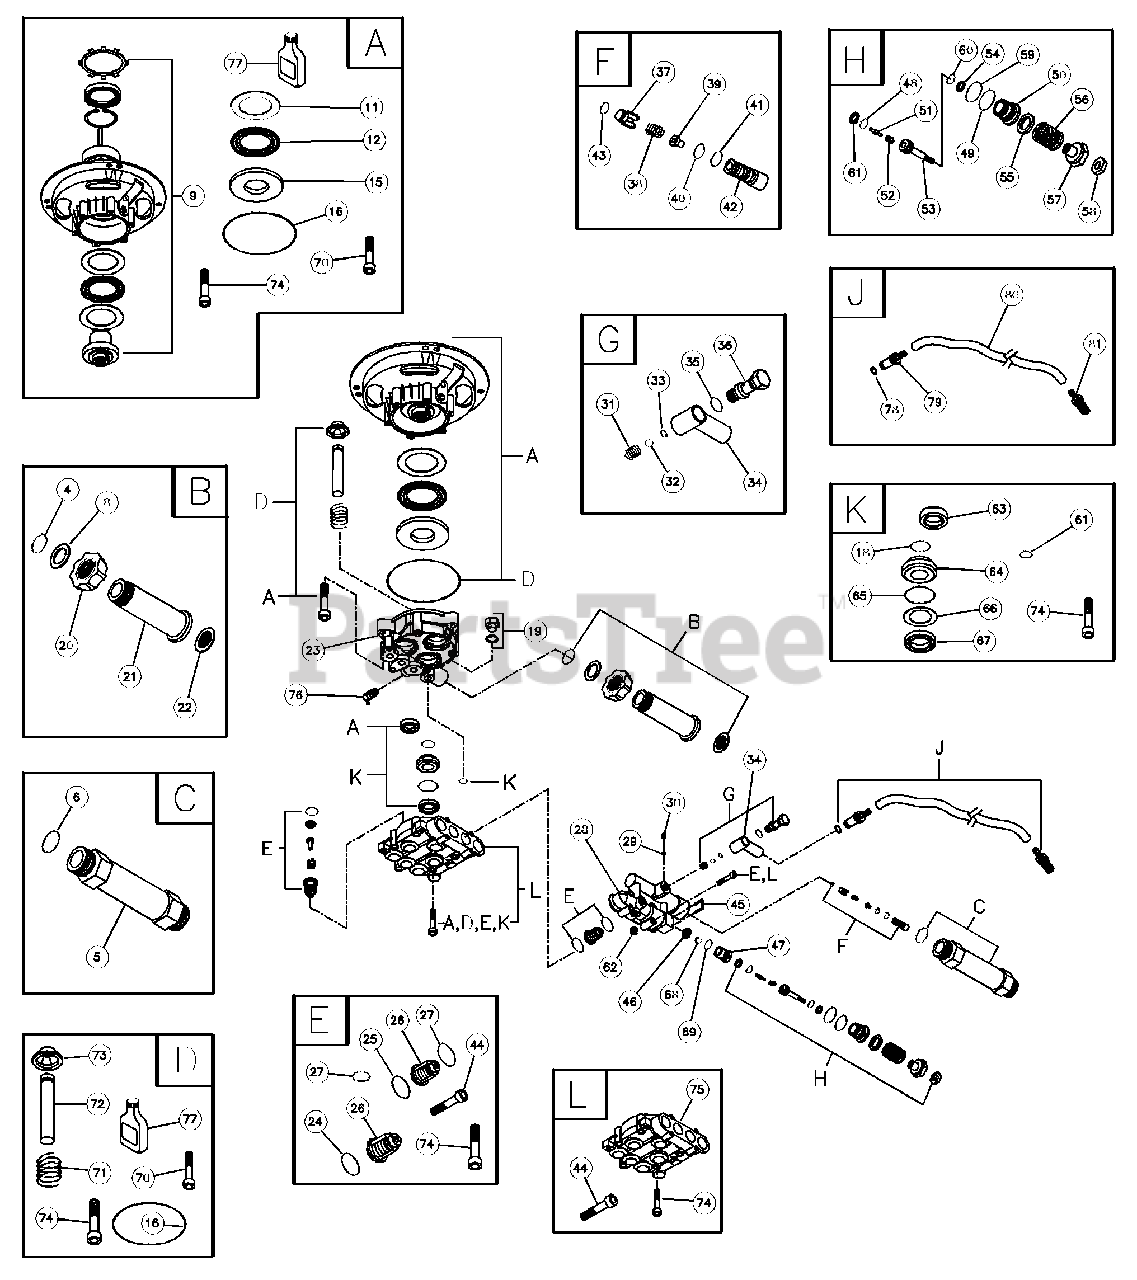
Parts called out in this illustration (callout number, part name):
4	O-RING
5	OUTLET EXTENTION
6	O-RING
8	WASHER
9	ASSY, Engine Adapter
11	FLAT BEARING DISC
12	ROLLER BEARING
15	FLAT BEARING DISC
16	O-RING
18	O-RING
20	GARDEN HOSE w/ FINGER GRIP
21	EXTENSION, INLET
22	WASHER w/ FILTER
24	O-RING
25	O-RING
26	ASSY, Valve Group
27	O-RING
29	O-RING
30	SCREW
31	SPRING
32	BALL
33	O-RING
34	CONNECTION, Chemical Inlet
35	O-RING
36	SCREW, Fitting
37	VALVE, Non-Return
38	SPRING
39	INJECTION NOZZLE
40	O-RING
41	O-RING
42	INJECTION NIPPLE
43	O-RING
44	SCREW
46	VALVE, Seat Plate, Brass
47	VALVE, Seat, Stainless
48	BACK RING
49	O-RING
50	VALVE, By Pass, Brass
51	PISTON
52	SPRING, Easy Start
53	PISTON, Body
54	RING, Back
55	SPACER
56	SPRING, Regulation Press
57	NUT, Regulation Press
58	NUT
59	O-RING
60	O-RING
61	O-RING
63	SEAL
64	PILOT SPACER, Brass
65	O-RING
66	WASHER
67	SEAL, H.P.
68	BALL, Stainless Steel
69	O-RING
70	SCREW
71	SPRING
72	PISTON, Stainless Steel
73	SPRING PLATE
74	SCREW
75	HEAD, Pump
76	THERMO RELIEF
77	OIL BOTTLE
78	O-RING
79	TUBE, Inlet Support
80	TUBE, Chemical
81	FILTER
A	KIT, WOBBLE PLATE BEARING
B	KIT, WATER INLET, ALUM
C	KIT, OUTLET, ALUM
D	KIT, PISTON
E	KIT,CHECK VALVES
F	KIT, INLET CHECK
G	KIT, CHEMICAL INJECTION
H	KIT, UNLOADER STEM
J	KIT, CHEMICAL HOSE
K	KIT, SEAL SET
L	KIT, HEAD BRASS
